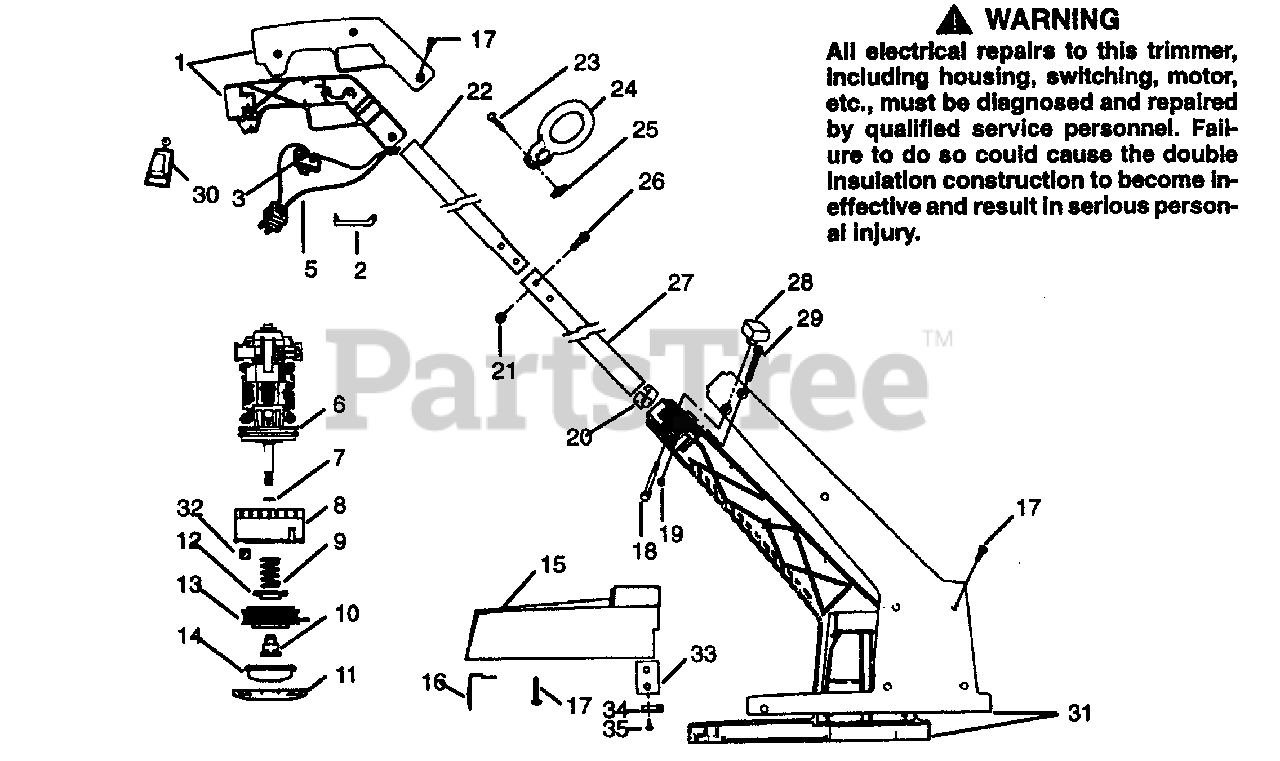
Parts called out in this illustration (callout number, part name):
1	Upper Handle Set US & Can Model 1214,1216
1	Upper Handle Set Model 1216
3	On-Off Switch
5	Wiring Harness
6	Motor Assembly Model 1214
6	Motor Assembly Model 1216
7	Washer
8	Hub Assembly w/line Saver
10	Drive Gear Assembly
11	Lock Ring
12	Spring Cap
13	Spool w/Line Model 1214
13	Spool w/Line Model 1216
14	Tap Button
15	Shield Type 2 & 3 Model 1214
15	Shield Type 1 & 2 Model 1216
15	Type 3 & Model 1216
16	Line Limiter Blade Model 1214 Type 1
16	Line Limiter Blade Type 2-3 & Model 1216
20	Snap Button
21	Lock Nut
22	Upper Tube
24	Assist Handle Model 1214
24	Assist Handle Model 1216
25	Wing Nut
27	Lower Tube English
27	Lower Tube French/English
30	Cord Retainer
31	Motor Housing Set Type 2-3 Model 1214
31	Motor Housing Set Type 1, 3, & Model 1216
31	Motor Housing Set Type 2 Model 1216
32	Foam Counterweight Model 1216
33	Line Limiter - Type 2-3 Model 1214
33	Line Limiter - Type 2 Model 1216
34	Blade Cover - Type 2-3 Model 1214
34	Blade Cover - Type 2 Model 1216
35	Screw Type 2-3 Model 1214
35	Screw Type 2 Model 1216
